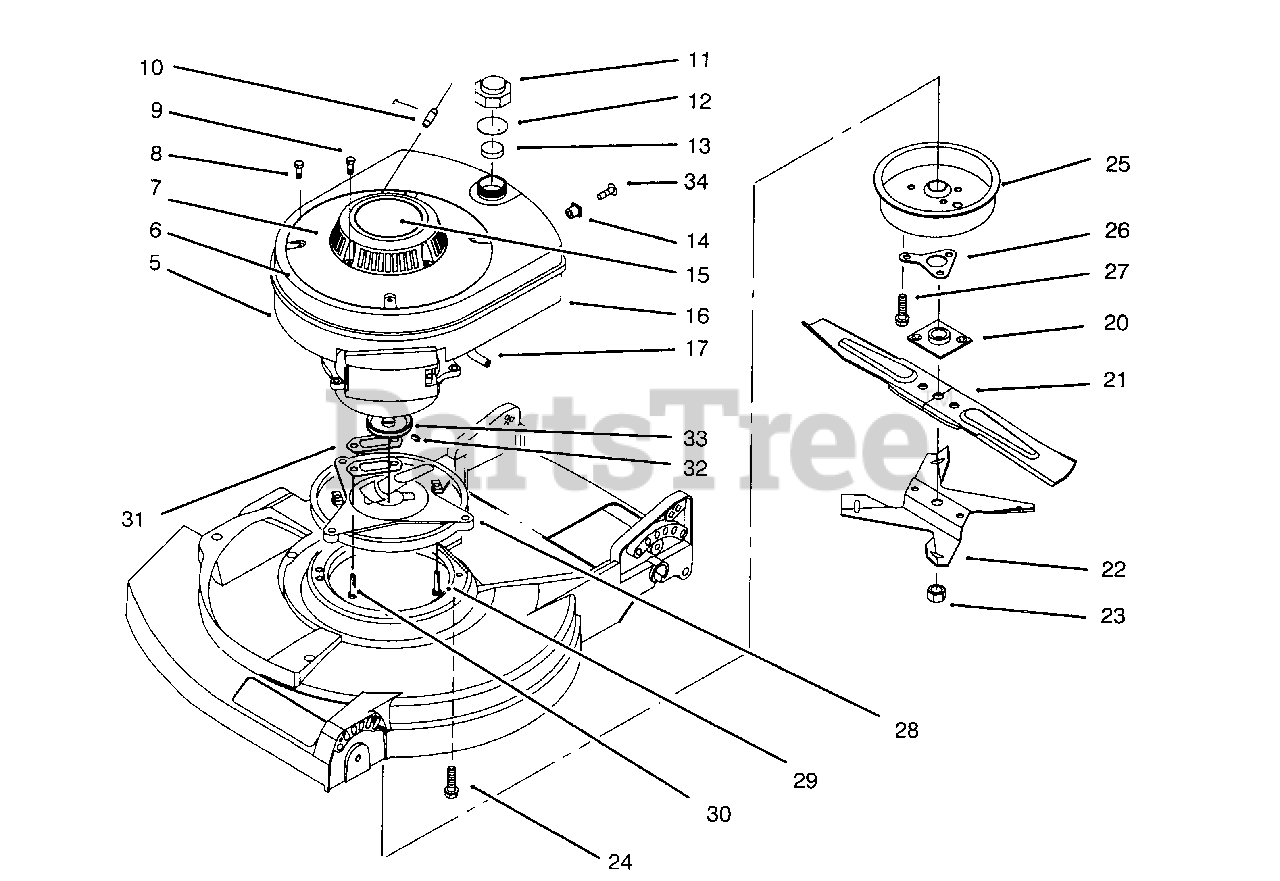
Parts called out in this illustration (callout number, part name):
5	Shroud & Tank Assembly
6	Base-Starter
7	Starter Assembly
8	Screw-Self Tapping
10	Stop-Rope
11	Cap-Fuel
12	Gasket-Fuel Cap
13	Baffle Fuel Cap
14	Grommet
15	Decal-Recoil (Model No. 10415)
16	Engine Assembly
17	Line-Fuel
20	Plate & Collar Assembly
21	Blade 21"
22	Fan-Mulching
23	Nut-Blade
24	Screw-Engine
25	Muffler Cover Assembly
26	Support-Crankshaft
28	Plate-Muffler
31	Gasket-Muffler
32	Screw-Set (Model No. 10515 & 10520)
33	Pulley (Model No. 10515 & 10520)
34	Screw-Self Tapping
